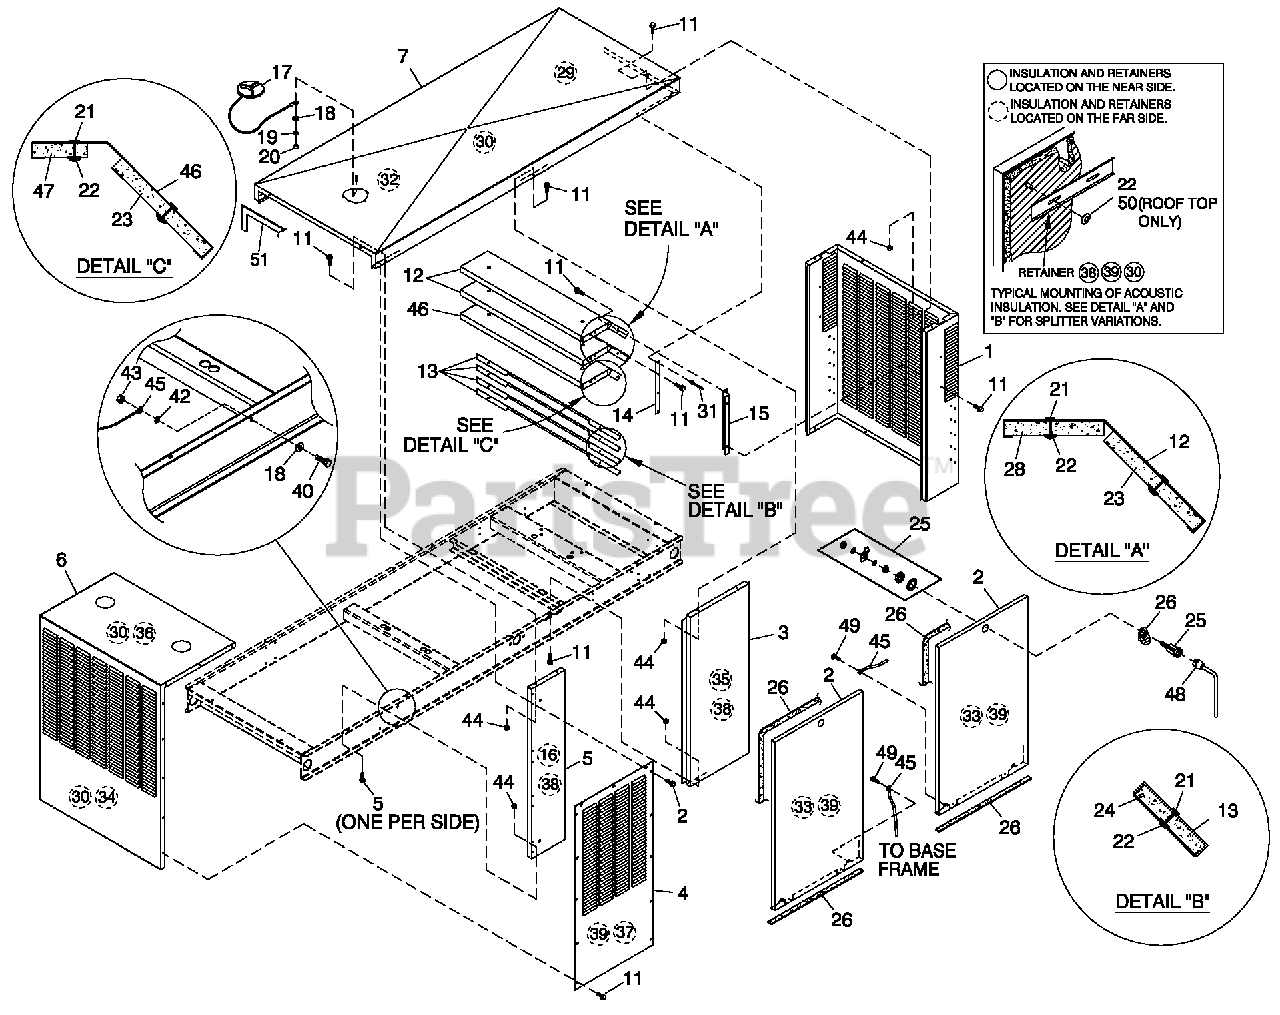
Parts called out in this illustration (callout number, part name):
1	REAR WRAP C5
2	DOOR C5
3	CENTER SUPPORT C5
4	DISCHARGE DUCT LH & RH SIDE C5
5	FRONT CORNERS C5
6	DISCHARGE CENTER DUCT C5
7	ROOF C5 ALUM
11	SCREW THF M6-1 X 16 N WA Z/JS
12	SPLITTER
13	SPLITTER SHORT
14	STRINGER SPLITTER C3
15	SUPPORT SPLITTER C5 130KW
16	INSULATION CORNER POST
17	ASSEMBLY COVER ACCESS
18	WASHER FLAT 1/4-M6 ZINC
19	WASHER LOCK M6-1/4
20	NUT HEX 1/4-20 STEEL
21	INSULATION RETAINMENT HANGER
22	WASHER SELF LOCKING DOME #4-40
23	INSULATION SPLITTER
24	INSULATION SHORT LOUVER
25	VISE-ACTION LATCH SLOTTED CIR
26	GASKET EXTRUDED TRIM (566" LG)
27	TAB PULL
28	INSULATION SPLITTER SML
29	INSULATION ROOF TOP REAR
30	RETAINER INSULATION (740)
31	RIVET POP .1875 X .450 SS
32	INSULATION ROOF TOP
33	INSULATION DOOR
34	INSULATION DISCHARGE DUCT
35	INSULATION CENTER SUPPORT
36	INSULATION DISCHARGE DUCT TOP
37	INSULATION INNER DUCT SIDE
38	RETAINER INSULATION (820)
39	RETAINER INSULATION (450)
40	SCREW HHC M6-1.0 X 20 G8.8
42	WASHER SHAKEPROOF INT 1/4
43	NUT HEX M6 X 1.0 G8 YEL CHR
44	NUT HEX LOCK M6-1.0 SS NY INS
45	ASSY WIRE 14 AWG 34.8" GRN/YEL
46	SPLITTER C5
47	INSULATION SPLITTER SHRT MPS
48	KEY VISE-ACTION LATCH SLOT CIR
49	SCREW TH-FRM M6 W/CAP SHKPRF W
50	WASHER SELF LOCKING DOME #8-32
51	STRIP SEALANT 1/8 X 1 (44.52"LG)
